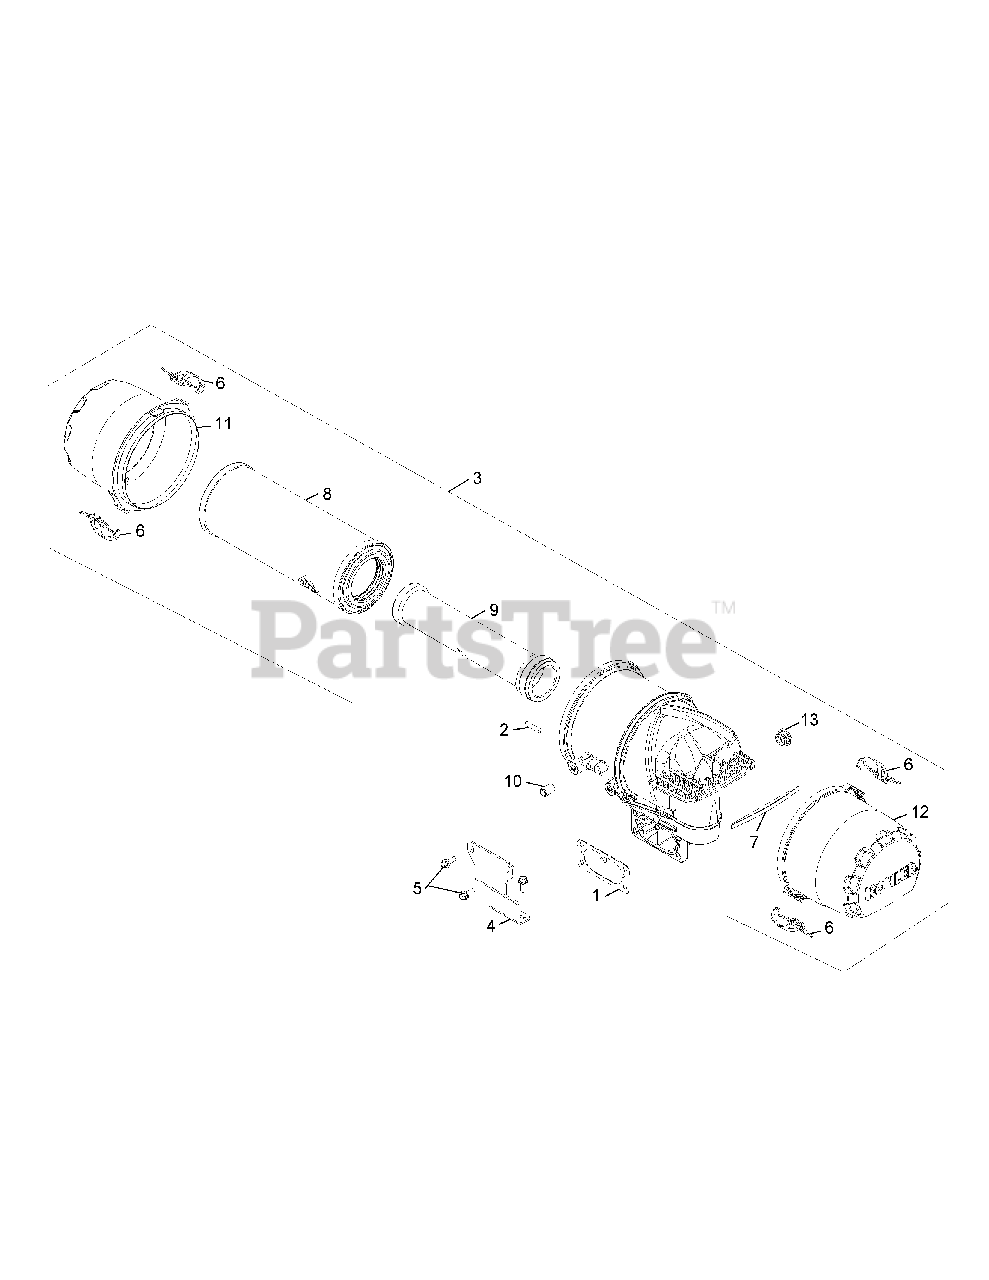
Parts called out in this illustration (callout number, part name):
1	Air Cleaner Gasket
3	Air Cleaner Kit
4	Support Bracket
5	Flange Screw, M6 x 1.0 x 16
6	Assembly Clip
7	Foam Insert Damper
8	Element, Air Filter - PRIMARY
9	Element, Air Filter - SAFETY
11	Air Filter Cover
12	Rain Cap Cover
